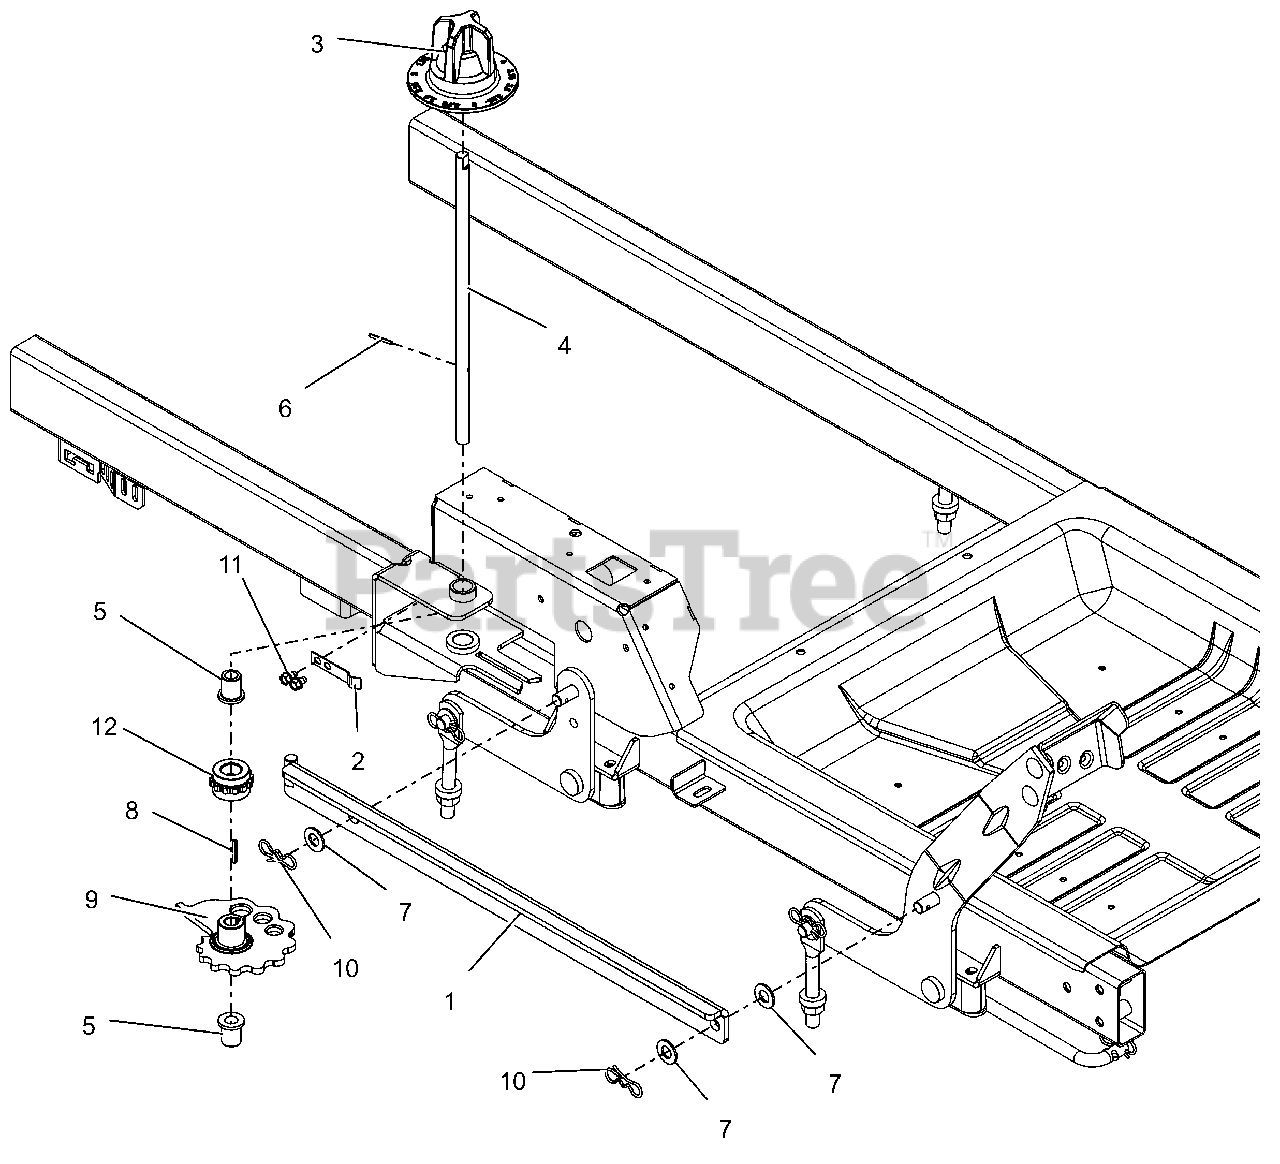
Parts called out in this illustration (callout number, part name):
1	WLDMT, HOC LINK
2	ARM, HOC DETENT
3	KNOB, HOC DIAL
4	SHAFT, HOC CAM
5	BSHG-FLG, .503X.750X.875X1.00
6	PIN-ROLL .125X1.00
7	WSHR-FL-NYL .518X1.000X.080
8	KEY, 1/8 X 1/8 X 1.0
9	CAM, HOC (PM)
10	PIN, BOWTIE .091X1.875 ZCC
11	SCR,TAP .25-20X.375 HWH TR ZCC
12	GEAR, HOC INDEX
